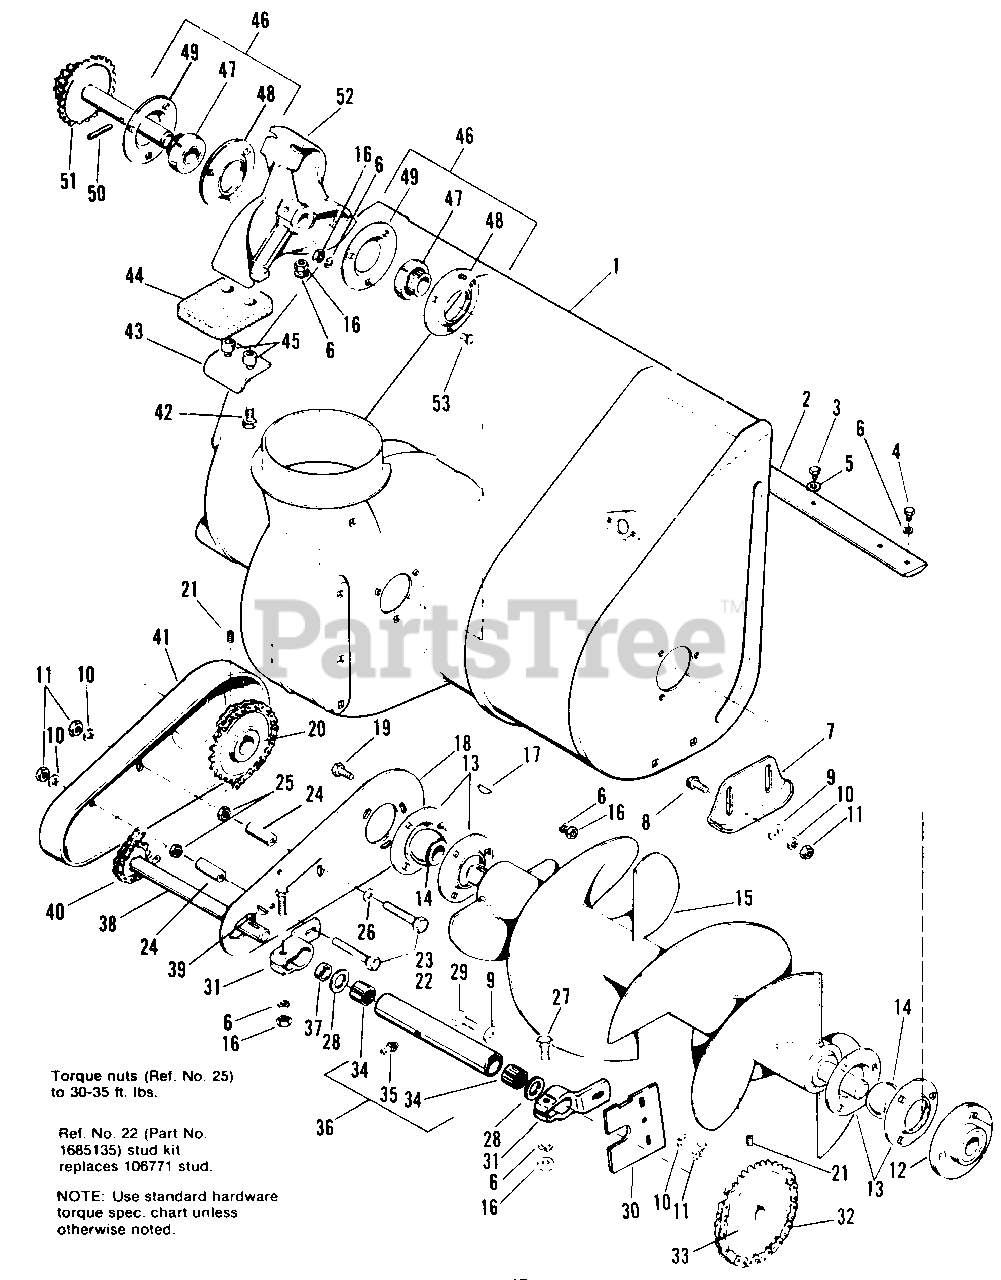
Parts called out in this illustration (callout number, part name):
1	BODY ASSY. (990551 Only)
1	BODY ASSY. (990656 Only)
1	BODY ASSY. (990643, 990796 & 1690255 Only)
1	BODY ASSY. (990652, 990742, 990869, 990870 & 1690209 Only)
2	SCRAPER, Body (990551, 990652, 990742, 990796, 990869 & 1690209 Only)
2	SCRAPER, Body (990643 & 1690255 Only)
2	SCRAPER, Body (990656 & 990870 Only)
3	SCREW, Hex, Taptite, 5/16-18 x 3/8
3	CAPSCREW, Hex Hd., 5/16-18 x 1/2
4	SCREW, Hex, Taptite, 1/4-20 x 3/8 (990551 Only)
5	WASHER, Plain, 1/4 (990551 Only)
6	LOCKWASHER, 5/16
8	BOLT, Carriage, 3/8-16 x 3/4
9	WASHER, Plain, 3/8 (Qty. 6 on 990551)
10	LOCKWASHER, 3/8 (Qty. 6 on 990551)
11	NUT, Hex, Full, 3/8-16
12	BEARING, Ball (990551, 990643, 990652, 990656 & 990742 Only)
13	FLANGE, Bearing
14	BEARING ASSY.
15	ROTOR ASSY.
15	ROTOR ASSY. (990643, 990796 & 1690255 Only)
15	ROTOR ASS.Y (990656 Only)
16	NUT, Hex, Full, 5/16-18
17	KEY, Woodruff
17	KEY, Woodruff, #15
18	PLATE, Side (990551 Only)
18	PLATE, Side
19	CAPSCREW, Hex, 5/16-18 x 3/4
21	SETSCREW, 5/16-18 x 5/16
22	STUD KIT (Includes Ref. Nos. 23, 24 & 25)
23	SCREW, Hex, Flange, Whiz, 3/8-16 x 2-1/4
25	LOCKNUT, Hex, Flange, 3/8-16
26	WASHER (990870, 1690209 & 1690255 Only)
27	CAPSCREW, Hex, 5/16-18 x 1-1/2
28	WASHER (Qty 2 on 990870, 1690209 & 1690255 Only)
29	CAPSCREW, Hex, 3/8-16 x 7/8
30	PLATE, Adjusting (Not used on 990551)
31	SUPPORT ASSY., Clamp
34	BEARING, Needle
35	FITTING, Grease
36	HOUSING, W/Bearing (990551, 990652, 990742, 990869 & 1690209 Only)
36	HOUSING, W/Bearing (990643, 990796 & 1690255 Only)
36	HOUSING, W/Bearing (990656 Only)
38	SHAFT ASSY.
38	SHAFT ASSY. (Used on 990643, 990796 & 1690255 Only)
38	SHAFT ASSY. (990656 Only)
39	KEY, Woodruff #9
41	GUARD, Chain (990551 Only)
41	GUARD, Chain
42	SCREW, Hex, Flange, Whizlock, 5/16-18 x 1-1/4
43	PLATE, Backup
44	BLADES, Impeller
46	BEARING REPLACEMENT KIT (Includes Ref. Nos. 47, 48 & 49)
50	PIN, Roll, 5/16 x 1-7/8
51	SPROCKET & SHAFT ASSY.
53	BOLT, Carriage, 5/16-18 x 5/8
